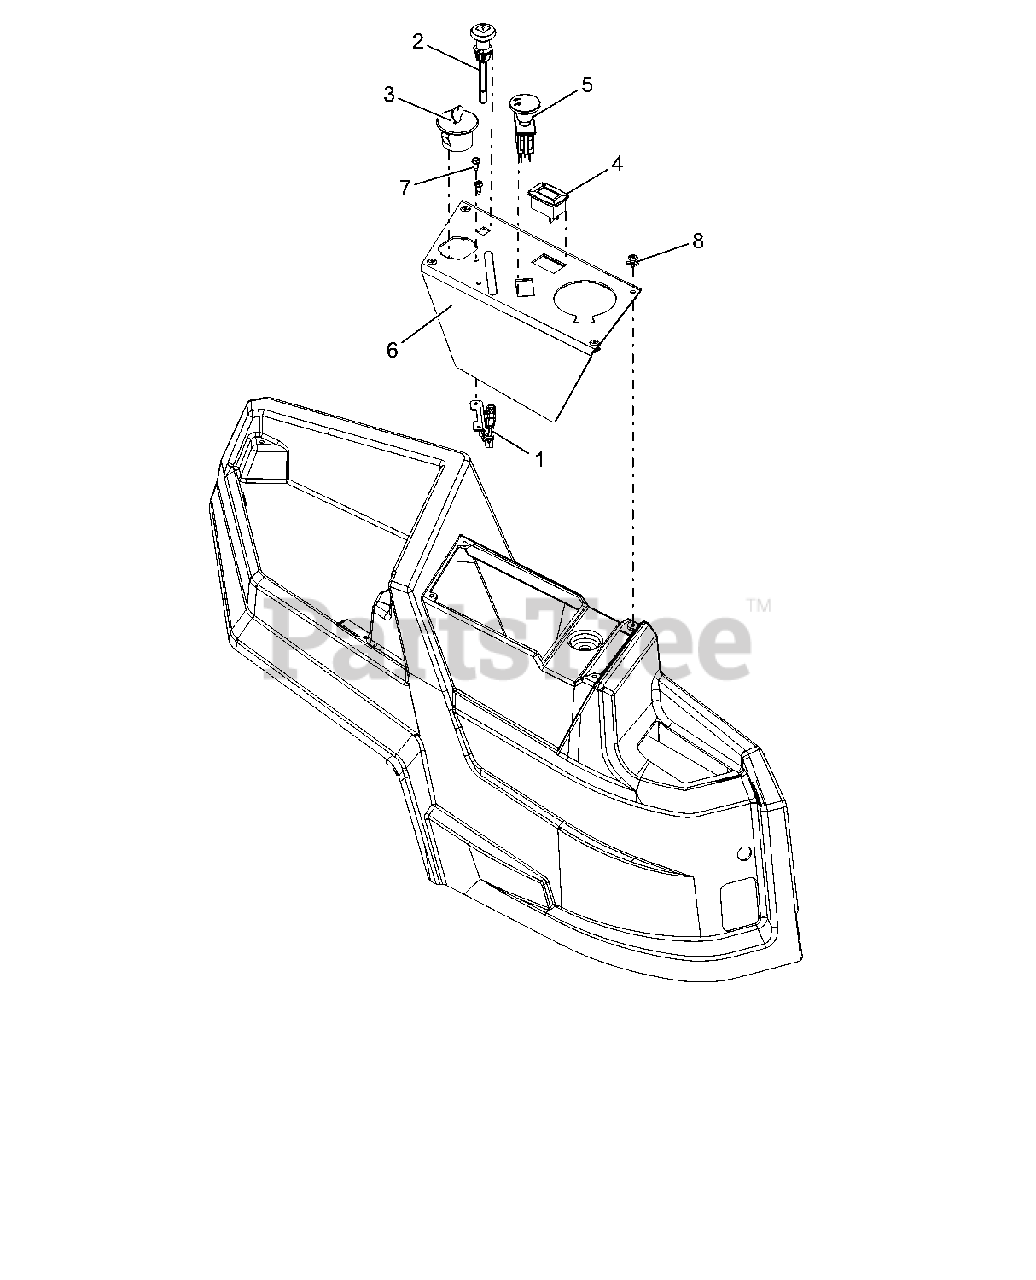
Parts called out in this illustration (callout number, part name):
1	CABLE - THROTTLE CONTROL
2	CABLE - CHOKE, SNAP-IN
3	KEYSWITCH-IGNITION 4 POS
3	KEYSWITCH-IGNITION 3 POS
4	METER, HOUR W/MAINTENANCE
5	SWITCH, CLUTCH (YELLOW)
6	PANEL, CONTROL
7	@SCR-TAP 10-24X.50 HWH TR YWZC
8	RIVET, PLASTIC .195 DIA.
